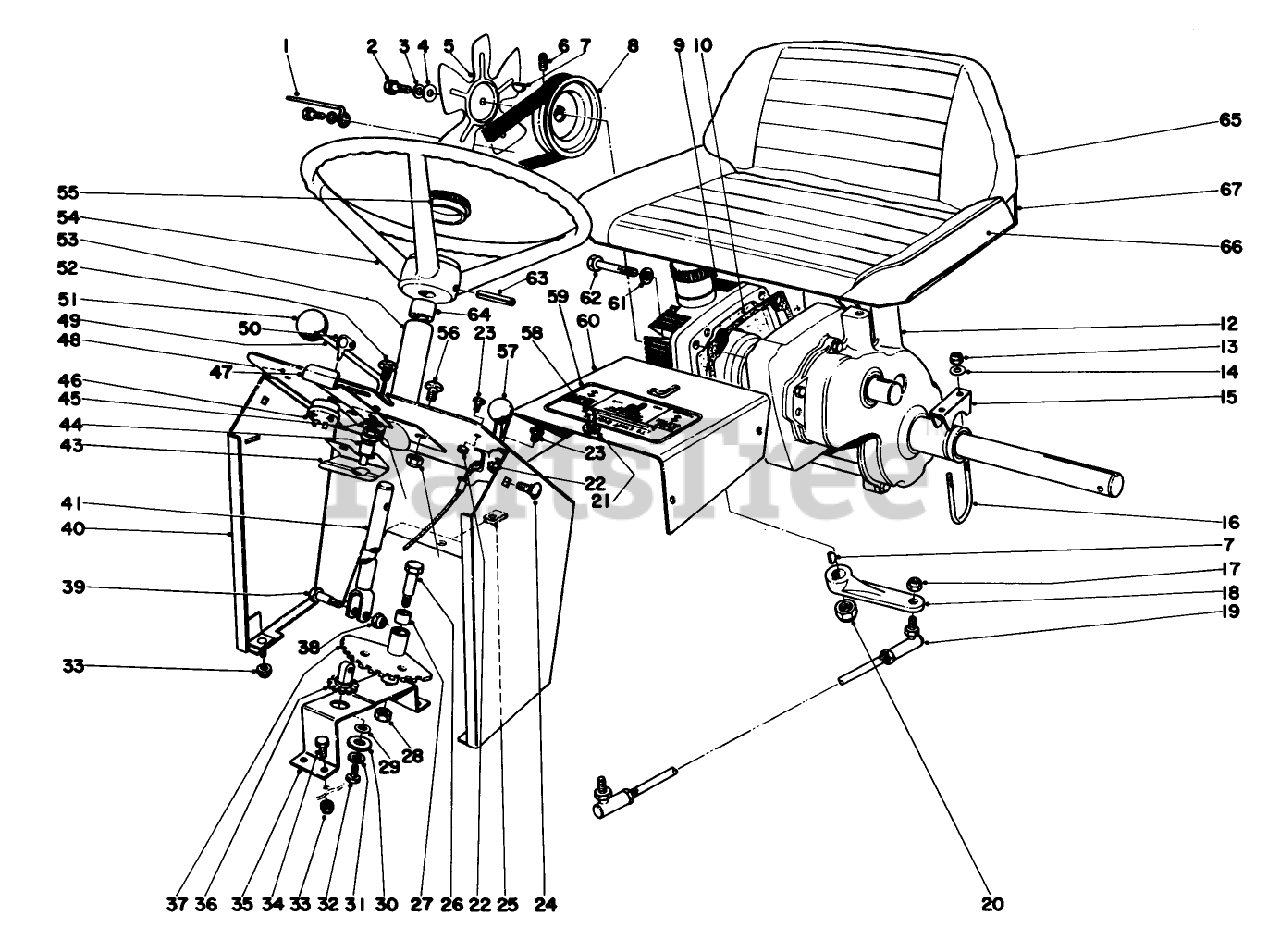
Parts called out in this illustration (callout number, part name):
1	Belt Guide
2	SCREW-HH
3	Lockwasher
4	WASHER-FLAT
6	SCREW-SET, HSH
7	KEY-WOODRUFF
8	Pulley
9	Hydrostatic Transmission
10	Gasket Transaxle
12	Transaxle
13	NUT-HEX
14	WASHER-FLAT
15	Axle Bracket
16	U-Bolt
17	NUT-HEX
18	Lever Hydrostatic
19	Control Rod Transmission
20	NUT-LOCK, CONE
21	WASHER-LOCK
22	Kep Nut
24	BOLT-CARR
25	SPEED NUT
26	Shoulder Bolt
27	BUSHING
28	Nut
29	Spacer
30	Washer
31	WASHER-LOCK
32	SCREW-HH
33	NUT-LOCK, CONE
34	SCREW-HH
35	Bracket
36	Pinion Steering
37	Gear Steering
38	NUT-HEX
39	Screw Shoulder
41	Steering Shaft
42	NUT-LOCK, CONE
43	Spring Detent
44	BUSHING
45	WASHER-FLAT
46	STARTER SWITCH
47	Hood Latch
48	Decal-Dash
49	Handle Hydro Control
50	Key
51	Knob
52	Carriage Bolt
53	Steering Tube Incl. Ref. #64
54	Steering Wheel
55	Steering Wheel Cap
56	Round Head Screw
57	Throttle Control
58	SCREW
59	Decal
60	Tunnel
61	WASHER-LOCK
62	SCREW-HH
63	PIN-ROLL
64	BUSHING
65	Seat Back
66	Seat Cushion
67	Frame-Seat
